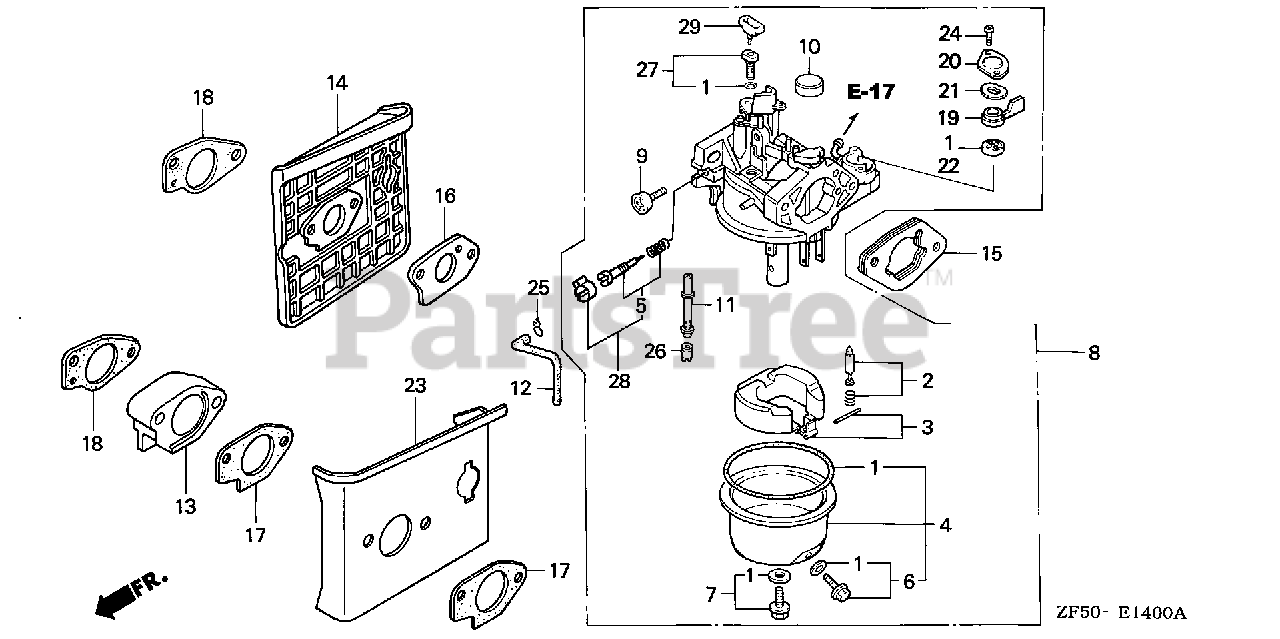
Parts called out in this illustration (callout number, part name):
1	GASKET SET (EXC. 16173-001-004) (CARBURETOR NO.) (EXCEPT 16173-001-004)
2	VALVE SET, FLOAT
4	CHAMBER SET, FLOAT
6	SCREW SET, DRAIN
7	SCREW SET
8	CARBURETOR ASSY. (BE86C A)
8	CARBURETOR ASSY. (BE86C B)
9	SCREW, THROTTLE STOP
10	CAP, CHOKE DUST
11	NOZZLE, MAIN
12	TUBE, AIR VENT (75MM)
14	INSULATOR, CARBURETOR
15	SPACER, CARBURETOR
16	GASKET, CARBURETOR
18	GASKET, INSULATOR
19	LEVER, PETCOCK
19	LEVER, PETCOCK (CARBURETOR NO.)
20	PLATE, LEVER SETTING
21	SPRING, PETCOCK LEVER
22	GASKET, PETCOCK (CARBURETOR NO.)
24	SCREW, PAN (3X6)
24	SCREW, PAN (3X8)
25	CLIP, TUBE (B8)
26	JET, MAIN (#90)
26	JET, MAIN (#92)
26	JET, MAIN (#88)
27	JET SET, PILOT (#40)
28	SCREW SET, PILOT
29	COLLAR, SETTING
